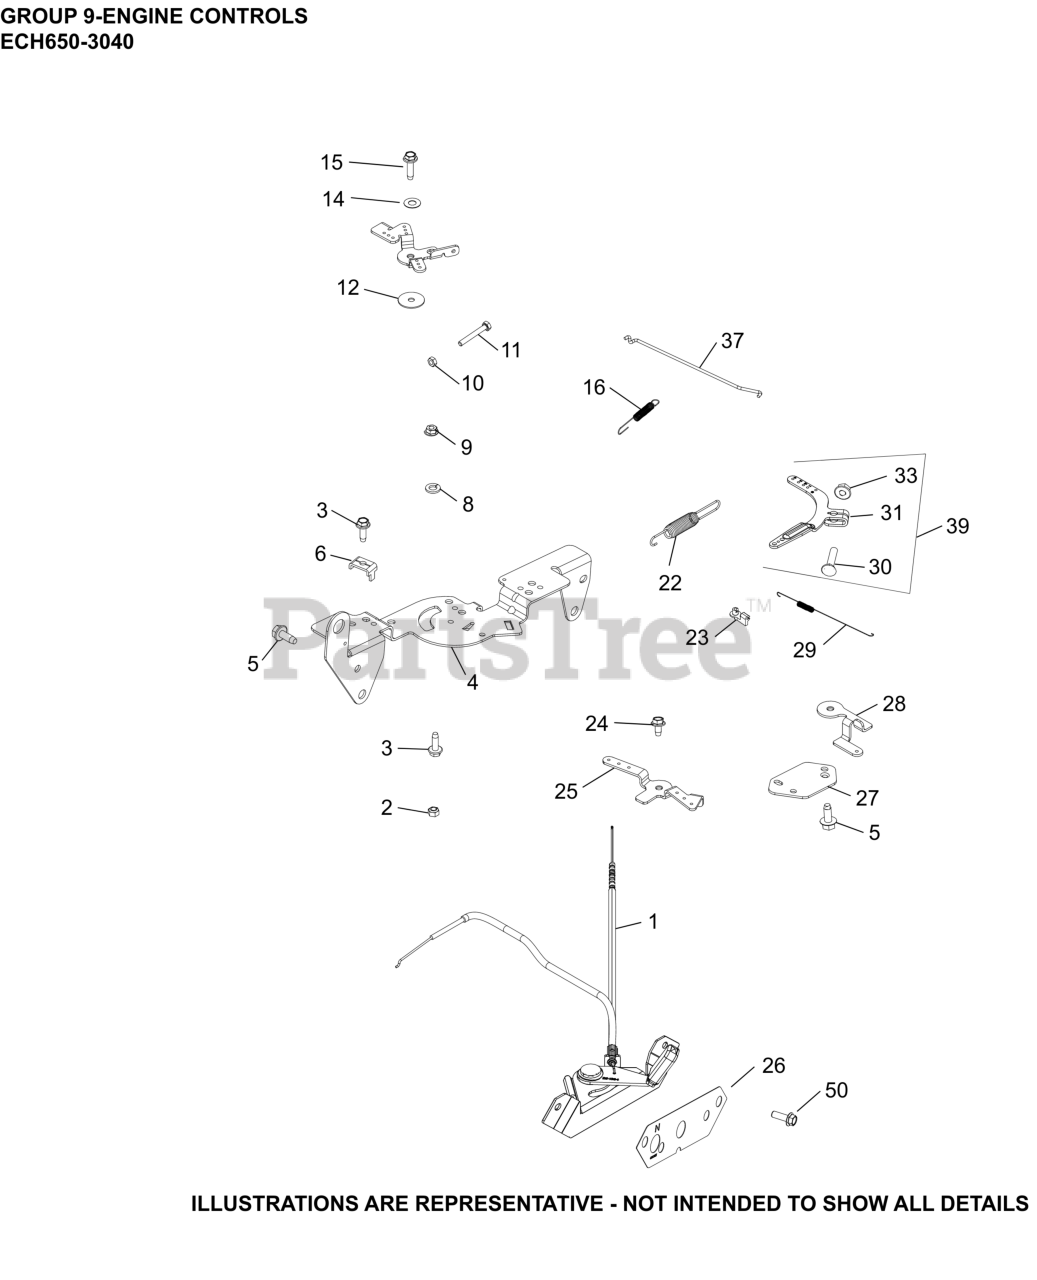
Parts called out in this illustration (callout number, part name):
1	CABLE, CONTROL ASSEMBLY
2	NUT, LOCK M5X.8
3	SCREW, THREAD FORMING
4	BRACKET, CONTROL
5	SCREW, THREAD FORMING
6	CLAMP, CABLE CABLE
8	WASHER, SPRING LOCK 1/4"
9	NUT, FLG M5X.8
10	NUT, M4X0.7
11	SCREW, CAP M4X.7X30
12	WASHER, FLAT 5.5 MM
14	WASHER, SPRING 1/4"
15	SCREW, THD FRM-USE 25 086 473-S
16	SPRING, THROTTLE LIMITER
22	SPRING, GOVERNOR (ORANGE)
23	BUSHING, THROTTLE LINKAGE
24	SCREW, THREAD FORMING
25	LEVER, THROTTLE CONTROL
26	LABEL, CONTROL PANEL
27	BRACKET, CABLE SUPPORT
28	LEVER, THROTTLE ACTUATOR
29	SPRING, LINKAGE
30	BOLT, RD HD SQ NECK M6X1.0X25
31	LEVER, GOVERNOR - (#2409069S)
33	NUT, FLG M6X1.0
37	LINKAGE, THROTTLE
39	LEVER, GOVERNOR ASSEMBLY
NI	SCREW, HI-LOW
